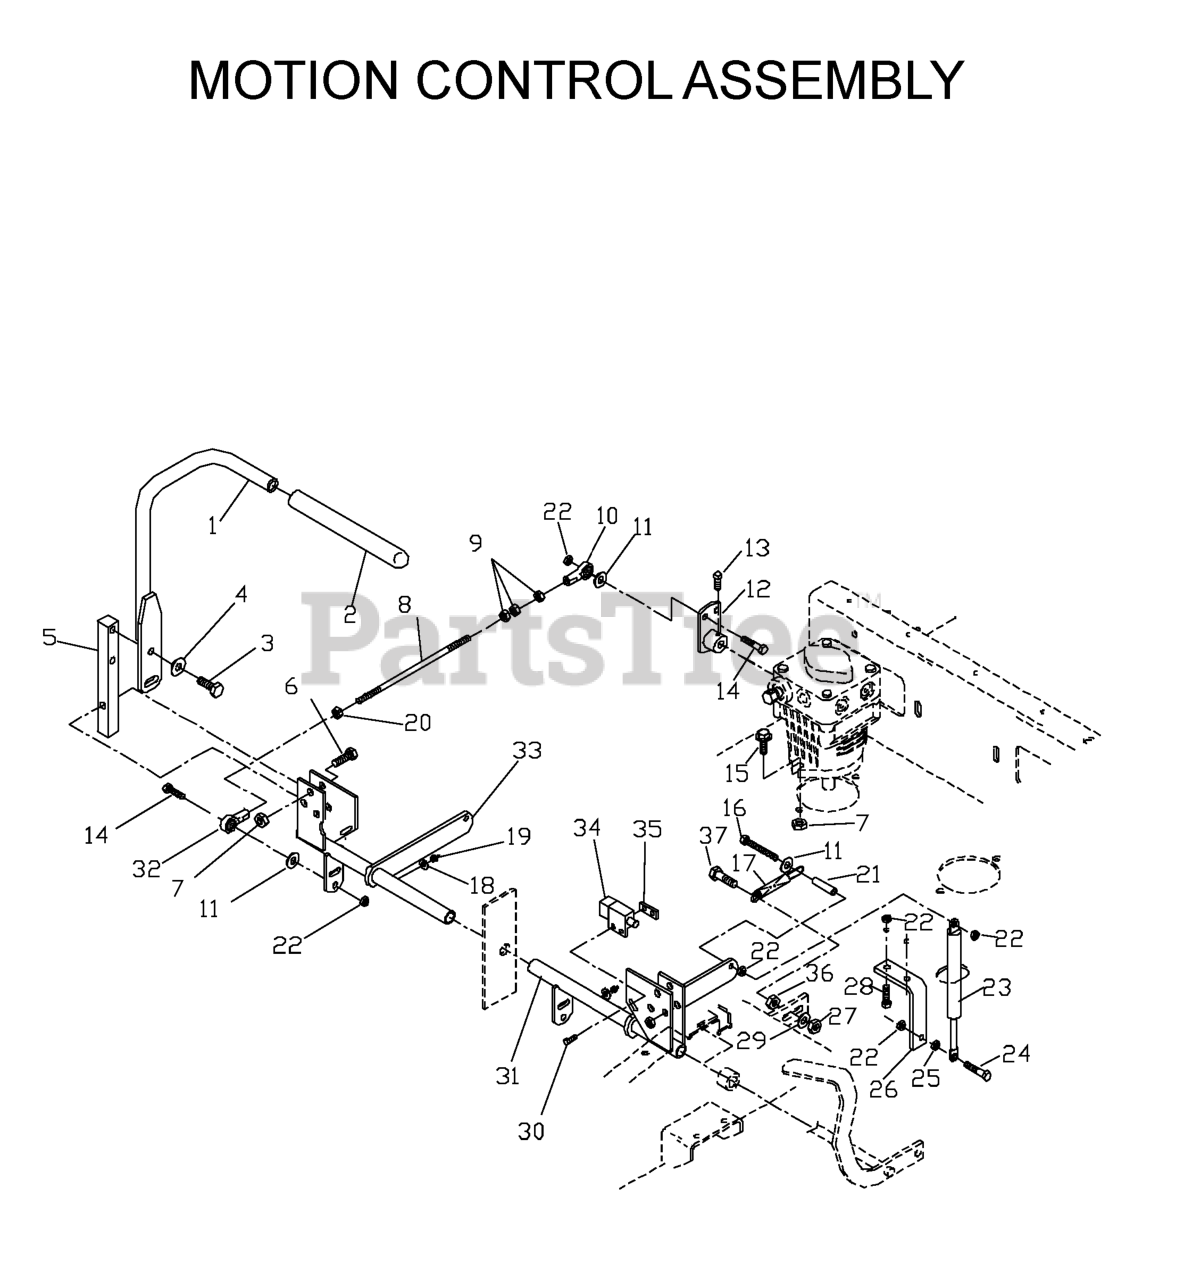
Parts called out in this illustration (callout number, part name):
1	CONTROL LEVER WELDMENT
3	HCS 3/8-16X1.GRD.5.ZD
4	WASHER, 3/8 DISC SPRING SPEC
5	CONTROL ARM
6	HCS 3/8C X 1 1/2
7	NUT 3/8C CENTERBLOCK
8	PUMP CONTROL LINK
10	BALL JOINT, RIGHT HANDED
11	WASHER 5/16 FLAT
12	PUMP LEVER
13	5/16C X 5/8 "V" POINT
14	HCS 5/16C X 1
15	4CS 3/8C X 1 SERRATED HEAD
16	TAP BOLT 5/16C X 2 1/4
19	ZERK
20	NUT 5/16F LEFTHAND
22	NUT 5/16C CENTERLOCK
24	HCS 5/16C X 1 1/4
25	NUT 5/16C WHIZ
26	BRACKET "I"
27	NUT 3/8-16 NYLOC
28	HCS 5/16C X 3/4
29	WASHER 3/8 FLAT
30	SCREW #10-24 X 5/8
31	CONTROL WELDMENT LT
32	BALL JOINT, LEFT HANDED
33	CONTROL WELDMENT RT.
34	SWITCH, INTERLOCK
35	TAPPED PLATE
36	NUT 3/8C WHIZ
37	HCS 3/8C X 2
